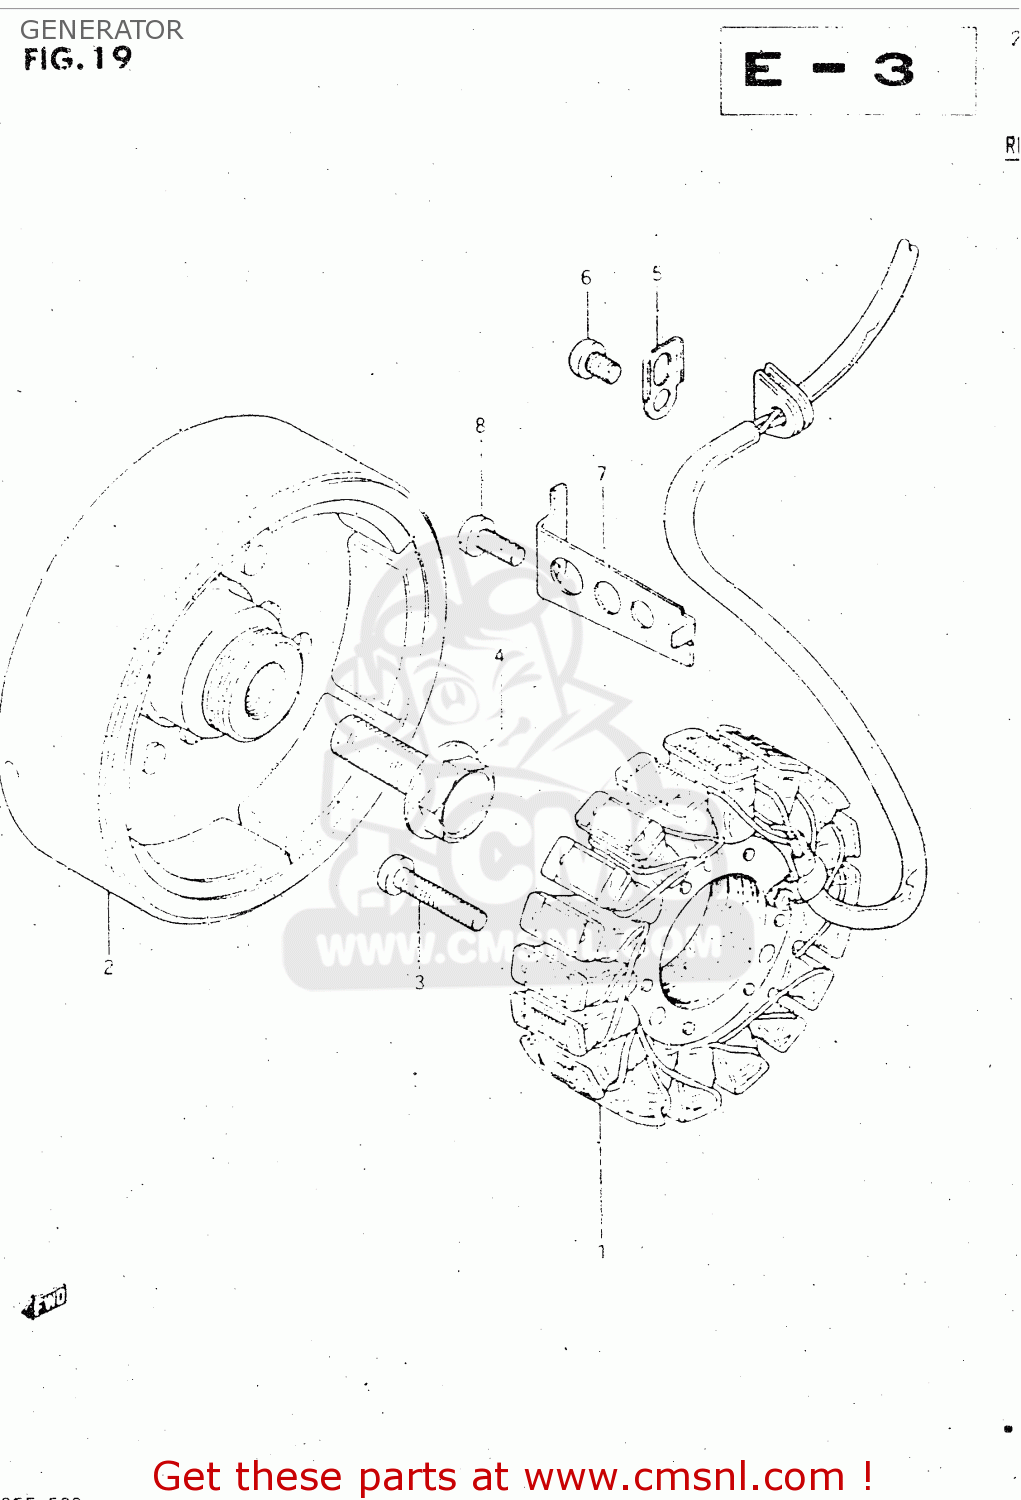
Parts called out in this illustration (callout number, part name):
1	STARTER ASSY
2	ROTOR ASSEMBLY
3	SCREW 6X30
4	BOLT(14X43)
5	CLAMP,GENERATOR LEAD WIRE
6	SCREW
7	CLAMP,GENERATOR LEAD WIRE
8	SCREW
